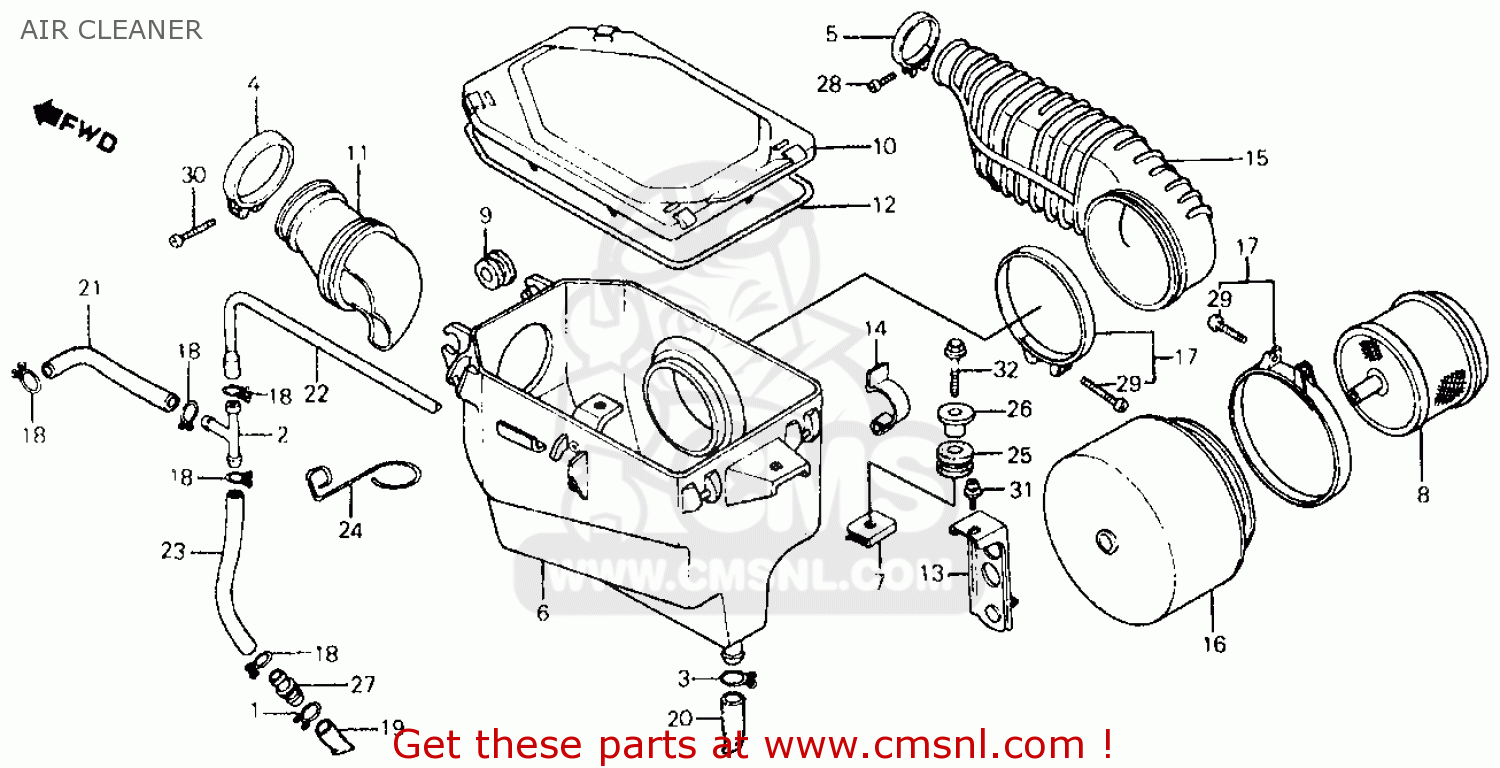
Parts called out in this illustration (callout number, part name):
1	CLIP,BRTHR TUBE
2	JOINT, BREATHER
3	CIR CLIP
4	BAND,INS
5	BAND,INSULATOR
6	CASE,AIR CLEANER
7	NUT,AIR/C CASE
8	BODY,AIR CLEANER
9	RUB,AIR/C CASE
10	LID,AIR/C CASE
11	TUBE,AIR/C INLET
12	SEAL,AIR/C COVER
13	STAY, A/CLNR ELEM
14	SPG,AIR/C CASE
15	TUBE,AIR/C CONN.
16	ELEMENT COMP.
17	BAND,AIR CLEANER
18	CLIP,TUBE
19	TUBE,DRAIN
20	TUBE, DRAIN
21	TUBE B,BREATHER
22	TUBE,BREATHER UP.
23	TUBE,BREATHER LOW
24	HLDR, BREATHER TUBE
25	RUBBER,FENDER MT.
26	COLLAR,FEND.MTG.
27	JOINT,TUBE
28	PAN SCREW 4X16
29	SCREW,PAN,4X20
30	SCREW,PAN,5X20
31	WASHER,SCREW 6X12
32	BOLT,FLANGE,6X25
